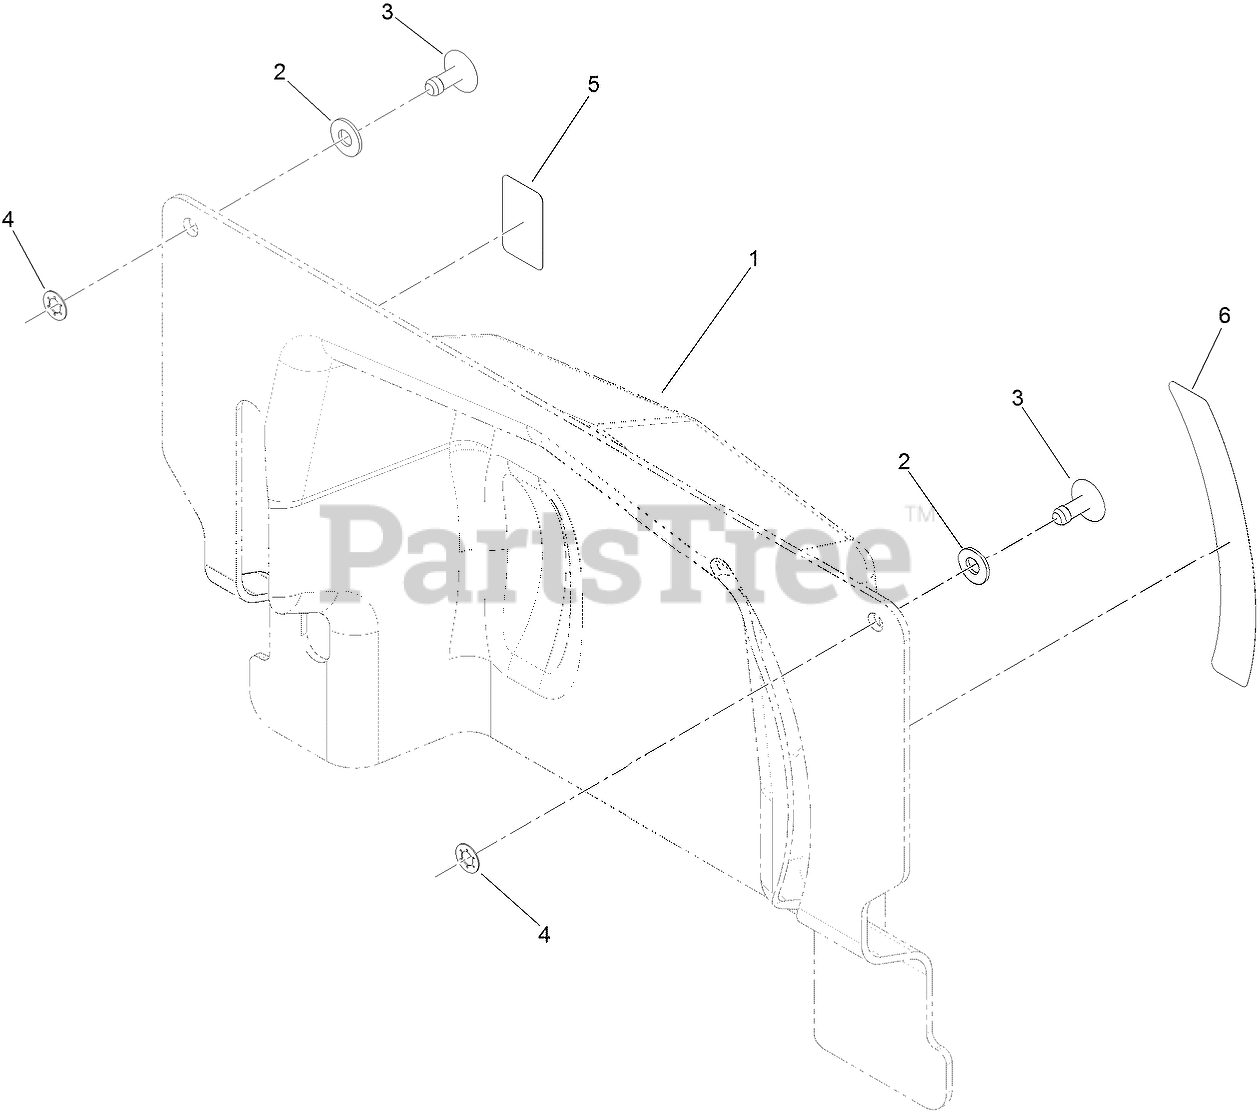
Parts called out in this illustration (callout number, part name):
1	Cover-Transaxle
2	WASHER-FLAT
3	STUD-1/4 TURN
4	RETAINER-STUD
5	DECAL-BRAKE, PARK
6	DECAL-RELEASE, DRIVE
